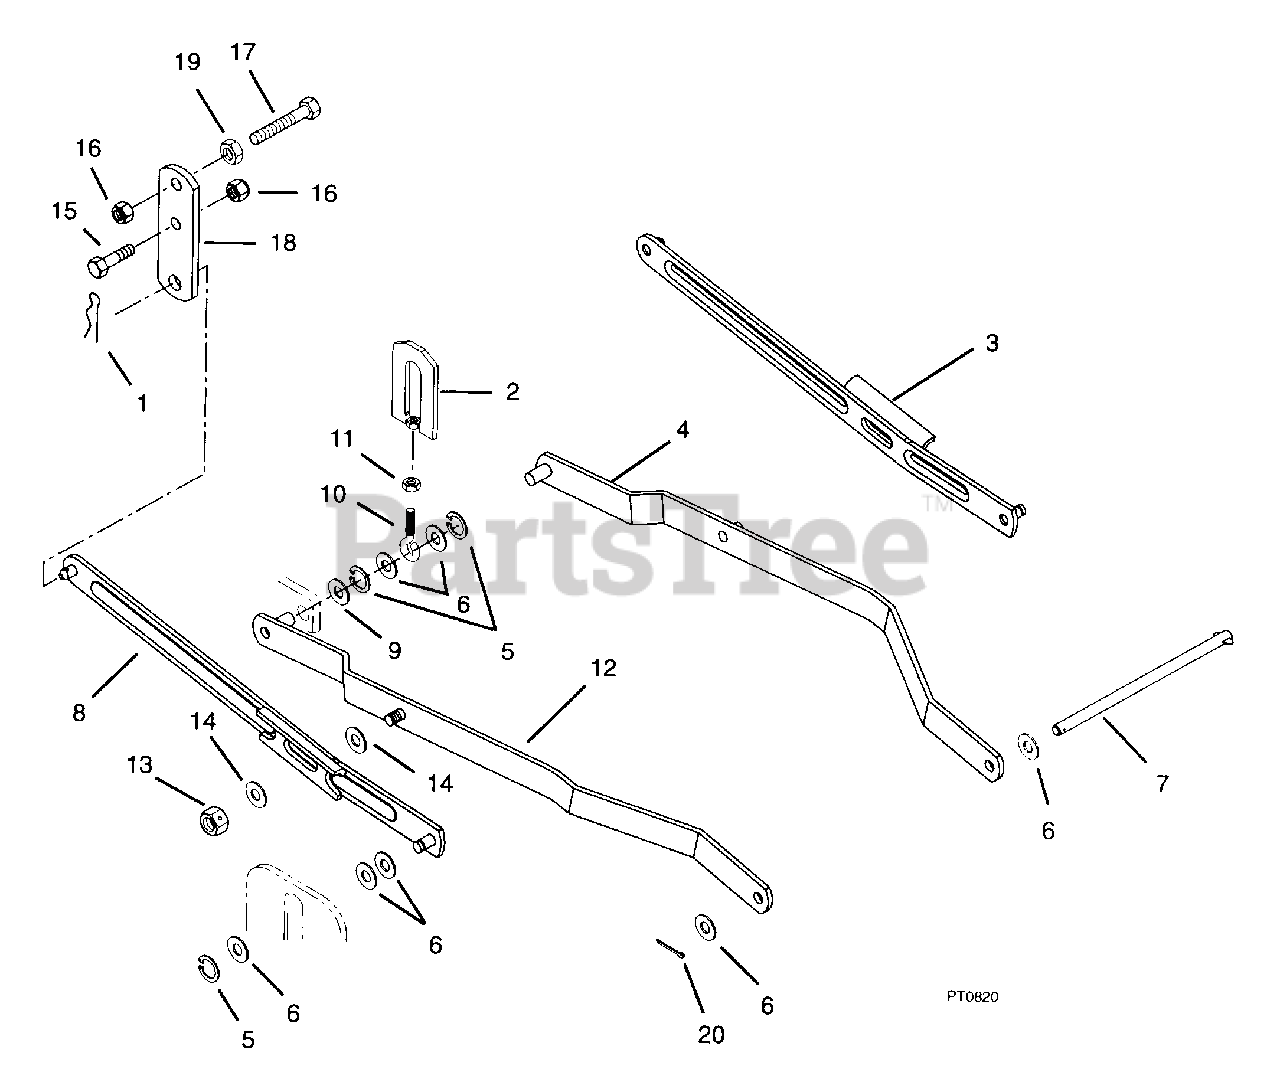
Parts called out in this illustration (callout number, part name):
1	PIN-HAIR EXT .12X.31X2.37 PL
2	LINK, ADJUSTMENT
3	REAR HANGER, L.H.
4	L.H. LIFT ARM
5	RG-RTNG-EXT .500X.050 (SNAP)
6	WSHR-FL-STL .531X1.062X.095 PL
7	PIN
8	REAR HANGER, R.H.
9	WSHR-FL-STL .531X1.250X.100 PL
11	NUT-JAM .375-16 PL
12	R.H. LIFT ARM
13	NUT-LK-CTR .625-11 TYP N
14	WSHR-FL-STL.656X1.312X.095 PL
15	BLT-HEX .38-16X.75 PL GR5
16	NUT-LK TOP .375-16 GR C YWZC
17	BLT-HEX .38-16X1.75 PL GR5
18	HANGER BRACKET
19	NUT-HEX .375-16
20	PIN-COTR .12X1.0 PL
